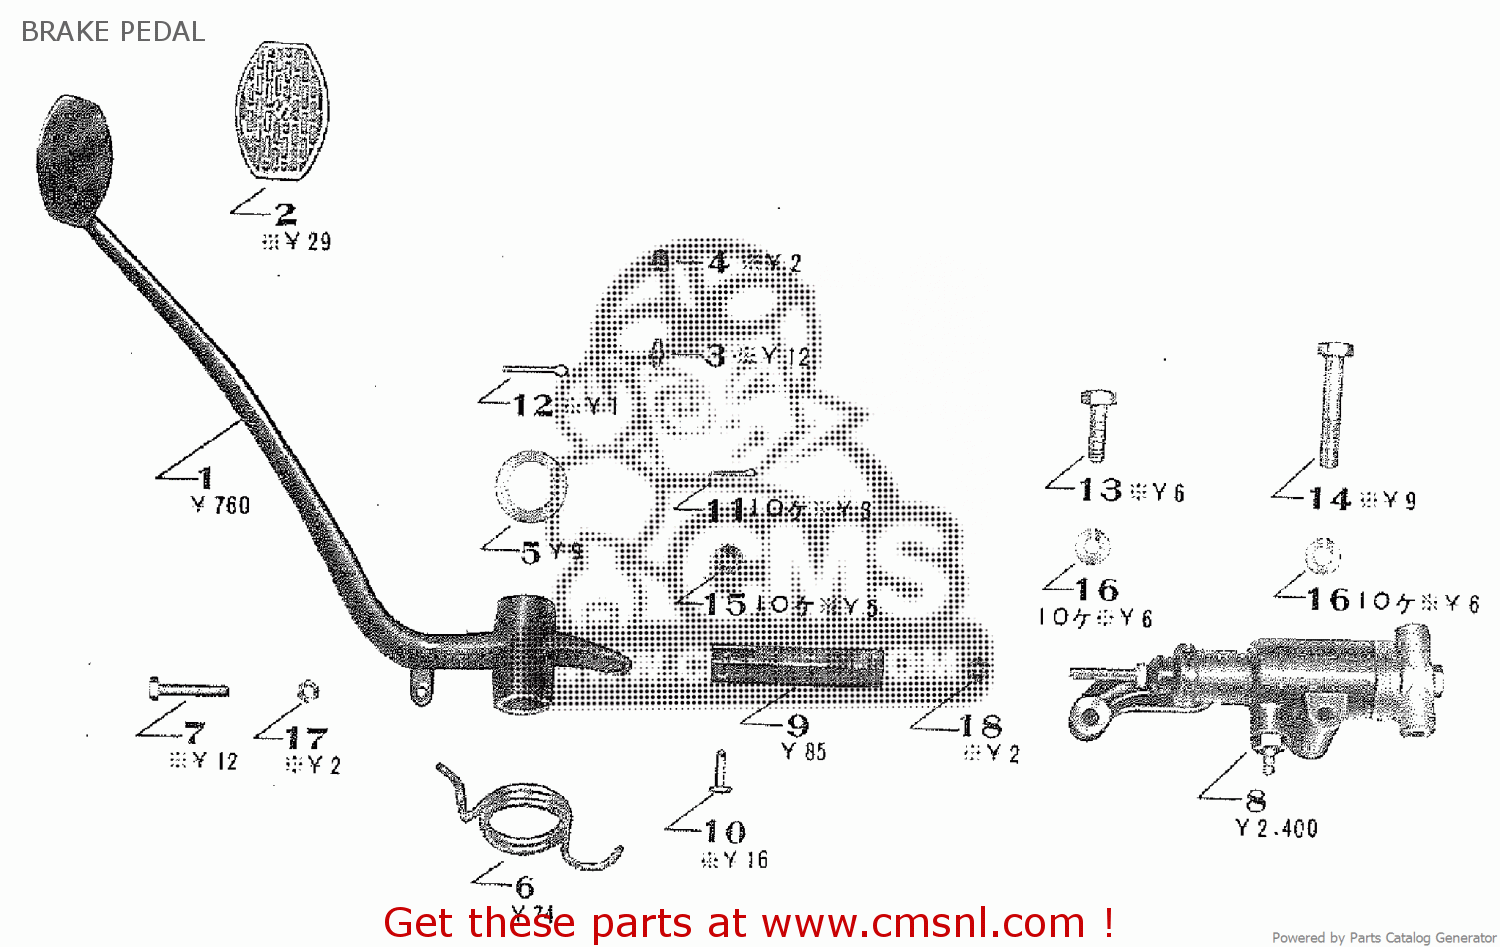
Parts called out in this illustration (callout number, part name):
1	BRAKE PEDAL COMP.
2	BRAKE PEDAL RUBBER
3	GREASE NIPPLE COMP.
4	GREASE NIPPLE CAP
5	BRAKE PEDAL SET WASHER
6	BRAKE PEDAL RETURN SPRING
7	STOP LAMP SWITCH PUSH ROD
8	MASTER CYLINDER ASSY.
9	PUSH ROD ADJUSTER
10	ADJUSTER JOINT PIN
11	2.0X12 COTTER PIN
12	3.0X30 COTTER PIN
13	8X25 HEXAGON BOLT
14	8X50 HEXAGON BOLT
15	6MM LIGHT PLANE WASHER
16	8MM SPRING WASHER
17	6MM HEXAGON NUT
18	6MM HEXAGON NUT
